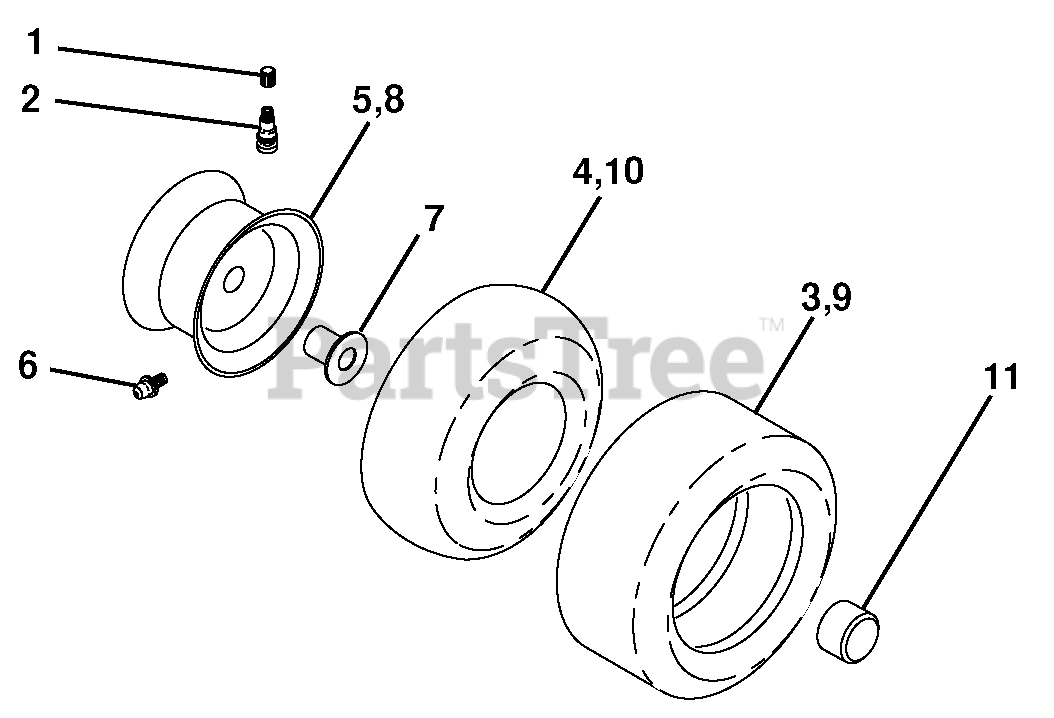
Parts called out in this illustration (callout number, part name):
1	Cap Valve Tire
2	Stem Valve
3	Tire F T 15 x 6 0 - 6
4	Tube Front)
5	Rim Asm 6" Front
6	Fitting Grease
7	Bearing Flange
8	Rim Asm 8" Rear
9	Tire R T 18 x 9.5-8 Turf Saver
9	Tire R T 18 x 9.5-8 Turf Saver LT
10	Tube Rear
11	Cap Axle Blk 1 50 x 1 00
11	Sealant, Tire (10 oz. Tube)
